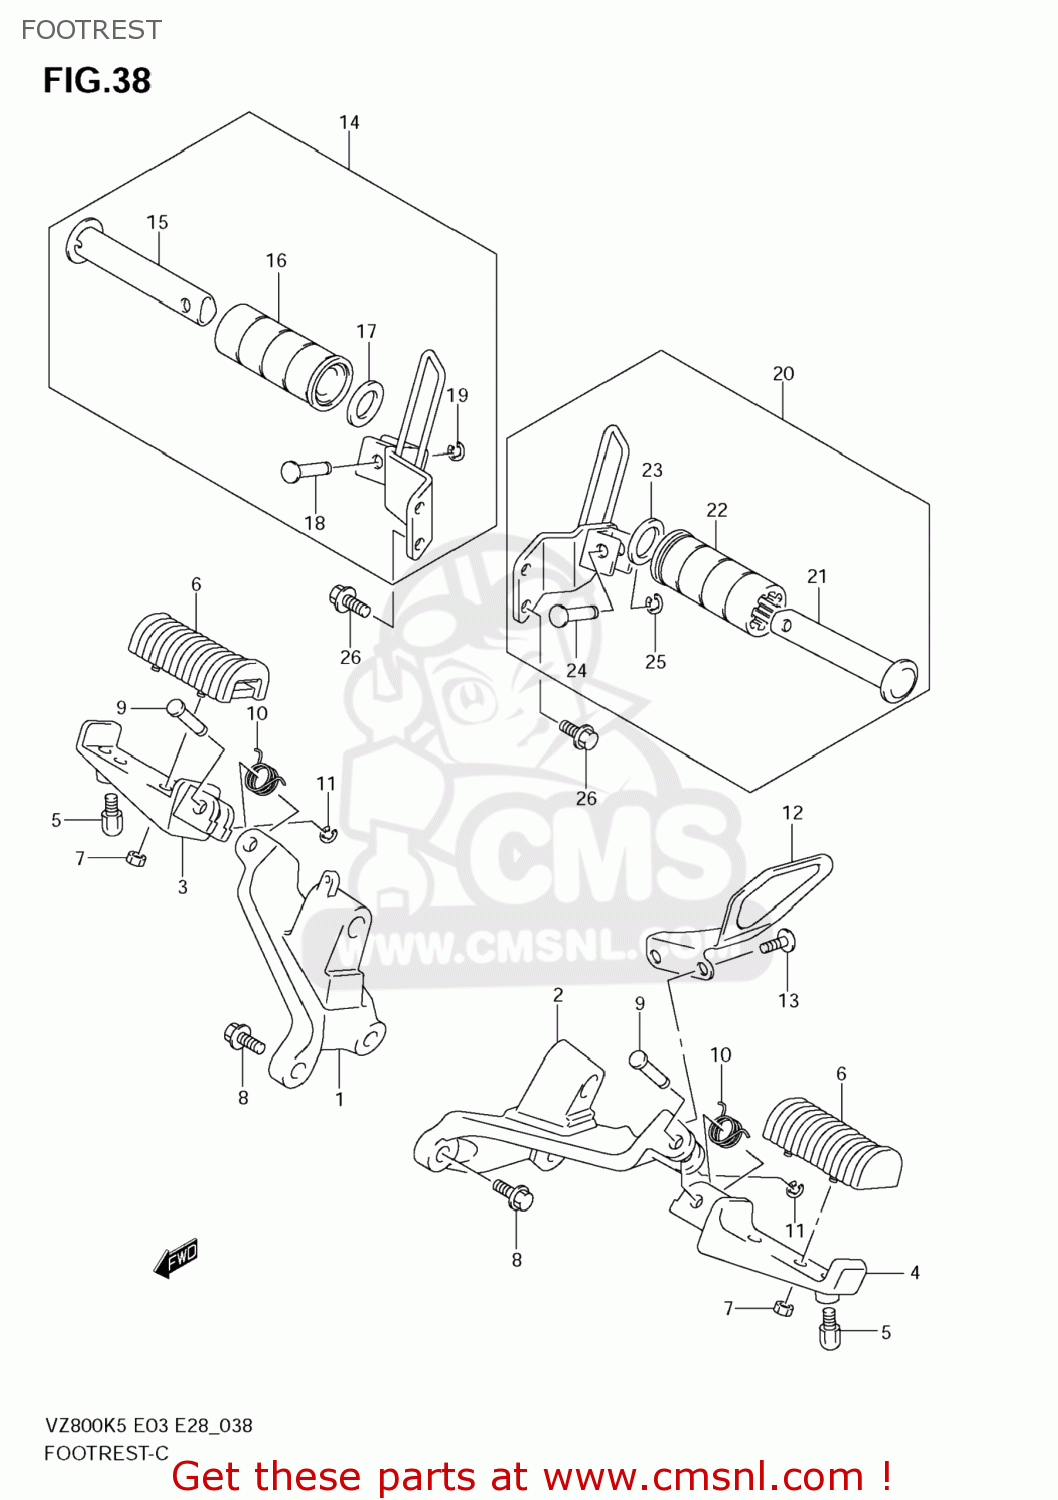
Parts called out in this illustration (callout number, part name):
1	BRACKET,FR FOOTREST,R
2	BRACKET,FR FOOTREST,L
3	BAR,FRONT FOOT
4	BAR,FRONT FOOT
5	BOLT,BANK SENSOR
6	RUBBER,FR FOOTREST
7	NUT
8	BOLT
9	PIN(8X33.2)
10	SPRING
11	E RING
12	GUARD,FR FOOTREST
13	SCREW(6X12)
14	FOOTREST ASSY,PILLION,R
15	BAR,PILLION FOOTREST
16	RUBBER,PILLION FOOTREST
17	WASHER(19.5X32X2)
18	PIN,PILLION FOOTREST
19	E RING
20	FOOTREST ASSY,PILLION,L
21	BAR,PILLION FOOTREST
22	RUBBER,PILLION FOOTREST
23	WASHER(19.5X32X2)
24	PIN,PILLION FOOTREST
25	E RING
26	BOLT(8X16)
